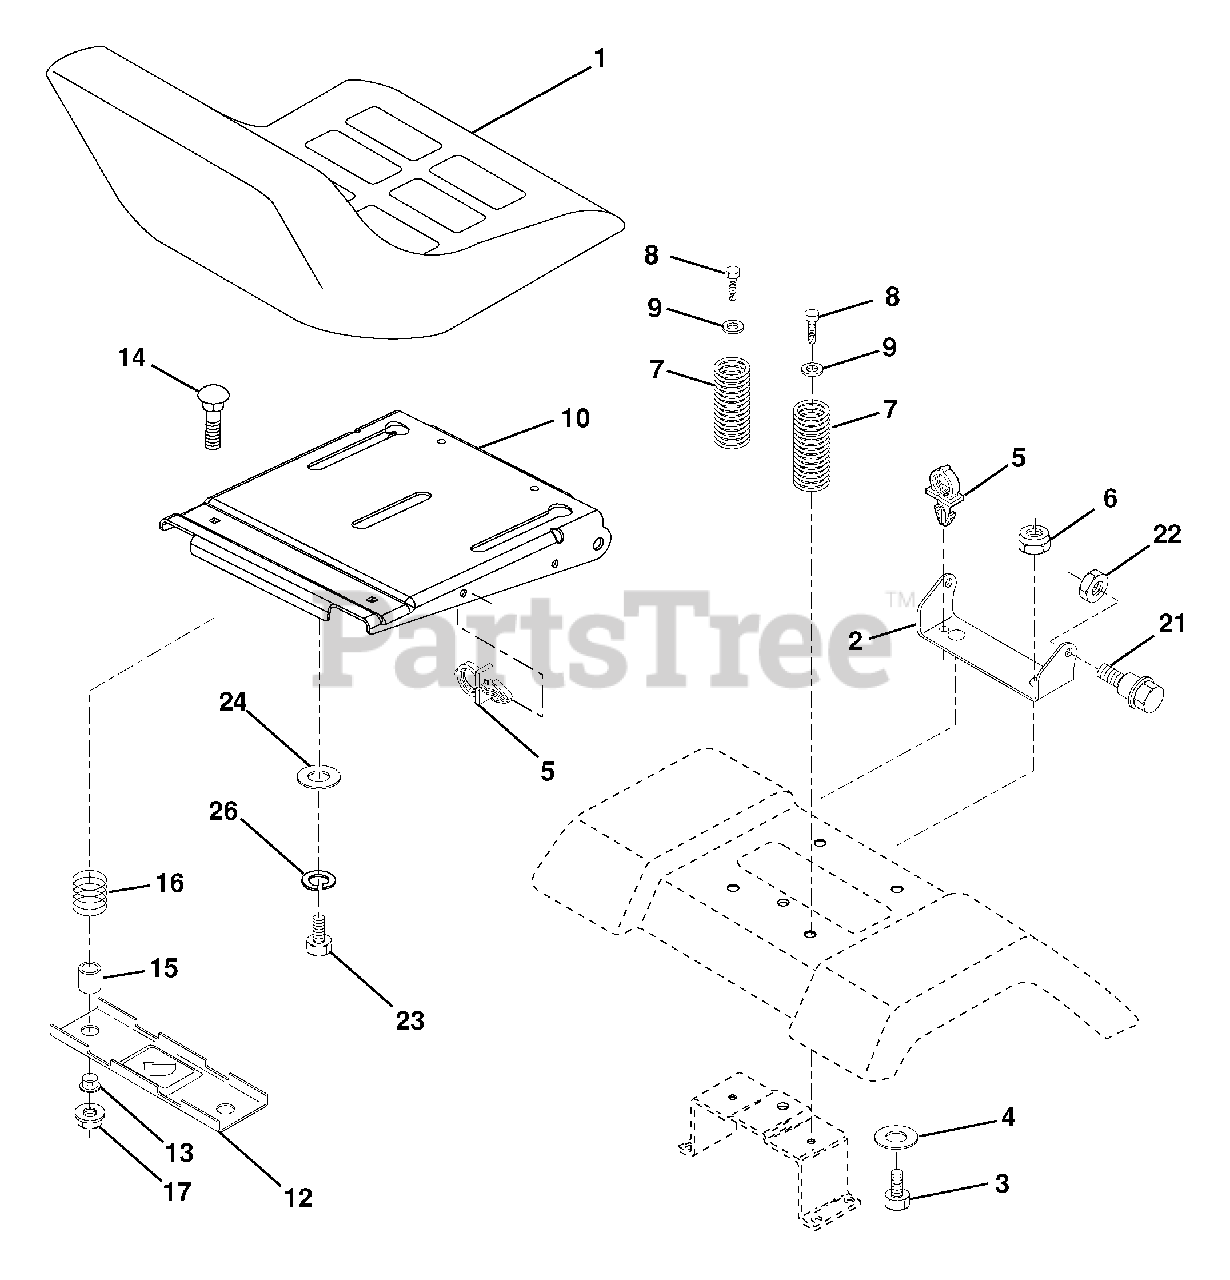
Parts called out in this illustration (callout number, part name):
2	Bracket Seat Pivot
3	Bolt Hex 3/8 - 16 x 1
4	Washer 13/32 x 1 x10 Ga.
5	Clip Push-In Hinged
6	Nut Lock Hex w/Ins 3/8 - 16
7	Spring Seat Cprsn 2 250 Blk Zi
8	Screw 3/8-16 x 1.5
9	Washer 13/32 x 1 x 14 Ga.
10	Pan Asm. Seat
12	Bracket Pnt Mounting Switch
13	Bushing Snap Blk Nyl
14	Bolt Rdhd Sht Nk 1/4 - 20 x 1 -1/2
15	Spacer Split .28 x .96
16	Spring Cprsn
17	Nut Lock 1/4 Lge Flg
21	Bolt Shoulder 5/16-18 unc-2A
22	Nut Lock Hex w/Ins 5/16 - 18
23	Bolt Hex
24	Washer 17/32 x 1-3/16 x 12 Ga.
26	Washer Lock Hvy Hlcl Spr 1/2
